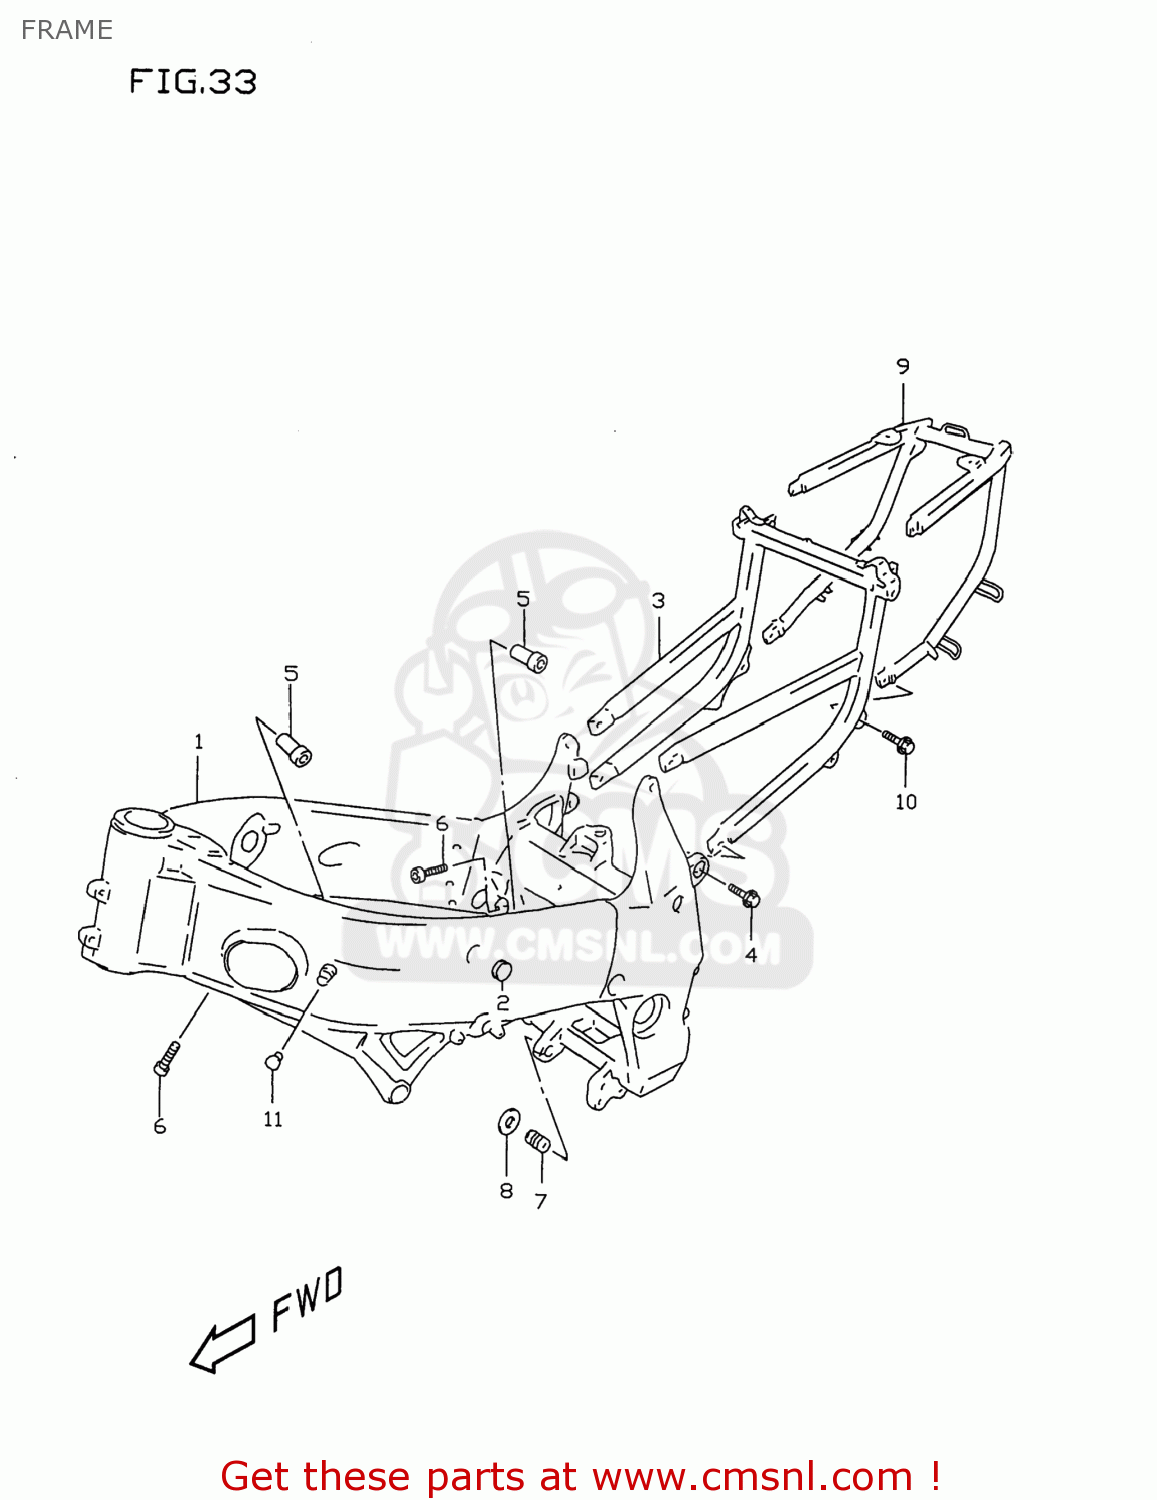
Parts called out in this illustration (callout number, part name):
1	FRAME COMP
2	CAP,TANK RAIL
3	RAIL,SEAT
4	BOLT(10X30)
5	SPACER,ENGINE MOUNTING
6	BOLT
7	BOLT,CRANKCASE ADJUST
8	NUT,CRANKCASE ADJUST
9	GRIP,RR
10	BOLT
11	CAP
